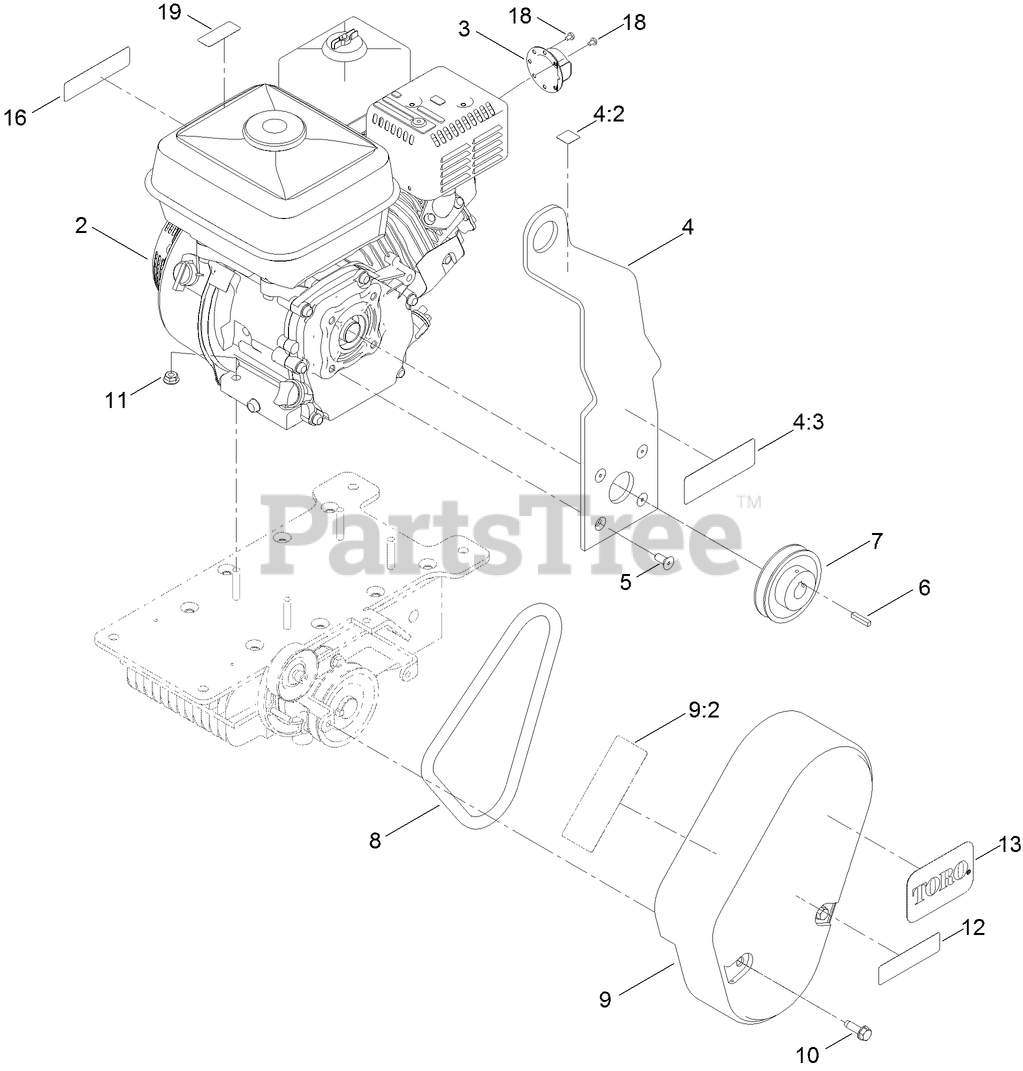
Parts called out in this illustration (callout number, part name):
3	DEFLECTOR
4	PLATE-EYE, LIFT
4:2	DECAL-POINT, LIFT
4:3	DECAL-WARNING
5	SCREW
6	KEY-SQUARE
7	SHEAVE
8	BELT-V
9	BELT GUARD ASM
9:2	DECAL-WARNING
10	SCREW-THD ROLL, HWH
11	NUT-FLANGE
16	DECAL-ARRESTOR, SPARK
18	SCREW-SELF TAPPING
19	DECAL-WARNING, ETHANOL
